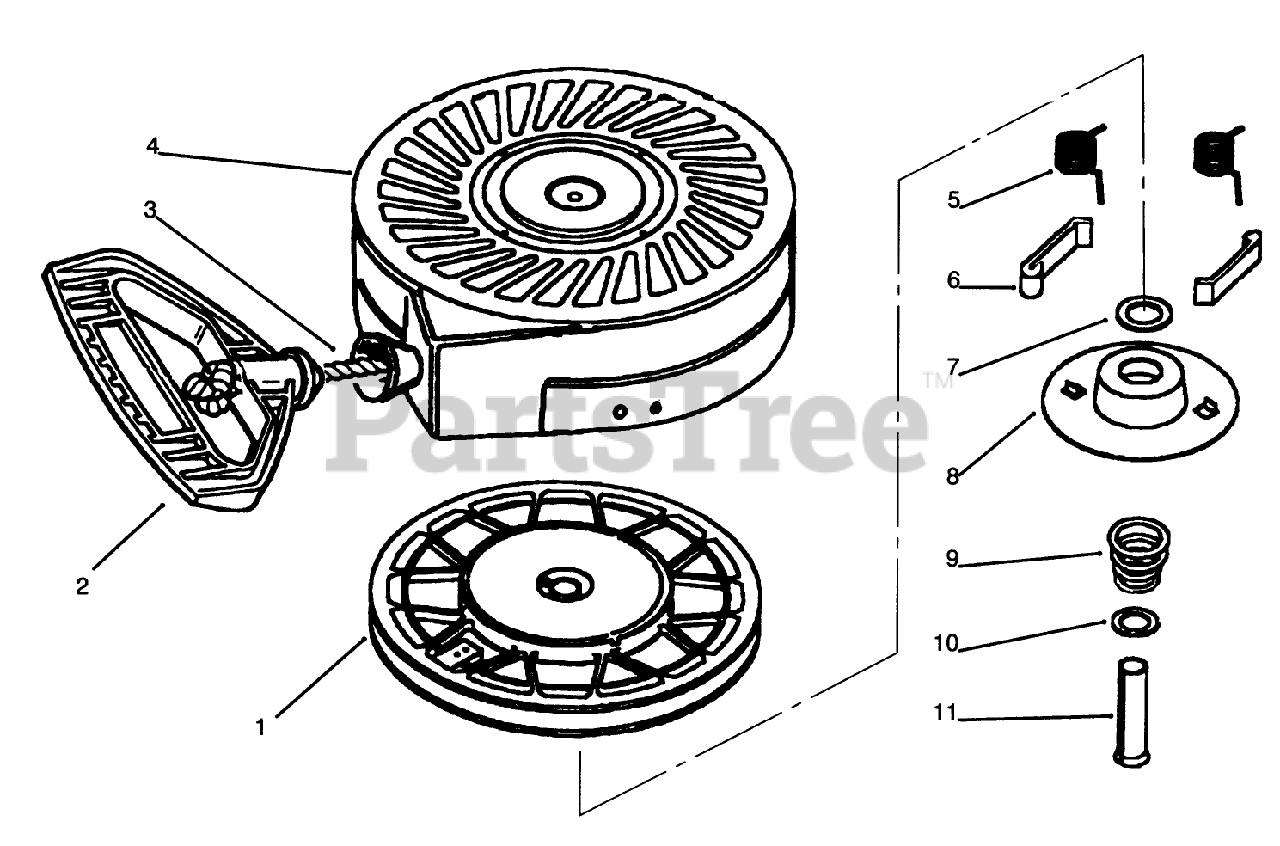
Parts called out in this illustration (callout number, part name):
1	Pulley and Rewind Spring ASM
2	Handle-Starter, Mitten Grip
3	Rope-Starter (98 cut to length)
4	Housing Assembly
5	Spring-Dog
6	Dog-Starter
7	Washer
8	Retainer
9	Spring-Brake
10	Washer
11	Pin, Spring (Incl. Ref. #7)
